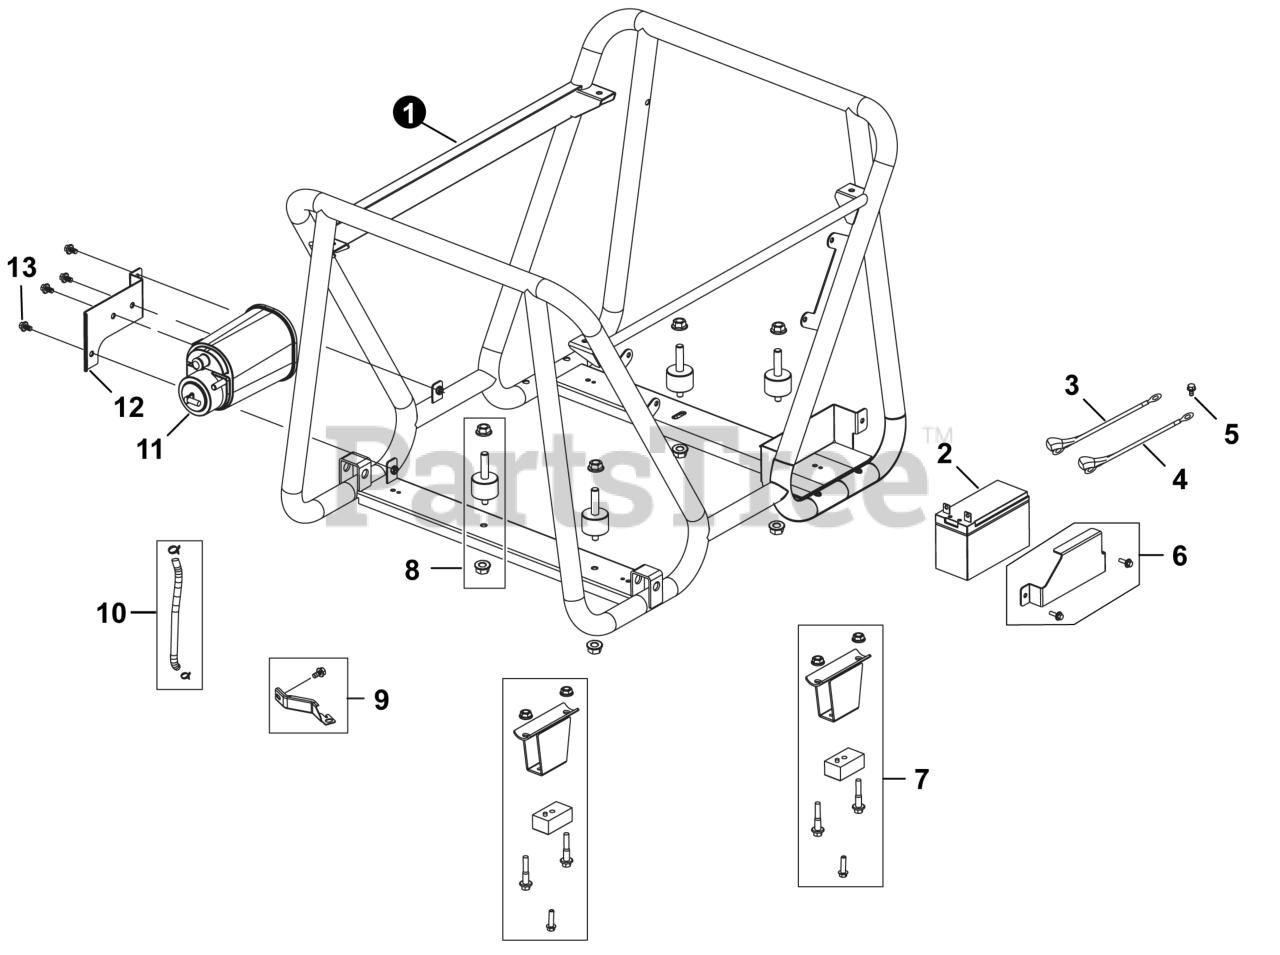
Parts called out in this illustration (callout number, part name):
1	FRAME ASSY, ENGINE
3	WIRE, ANODE
4	WIRE, CATHODE
6	CLAMP, BATTERY
7	MOUNT, ENGINE
8	CUSHION, ENGINE FRAME
9	SUPPORT, ATR CLEANER
10	HOSE, AIR CLEANER
11	CANNISTER, VAPOR
12	PLATE, VAPOR CANNISTER
